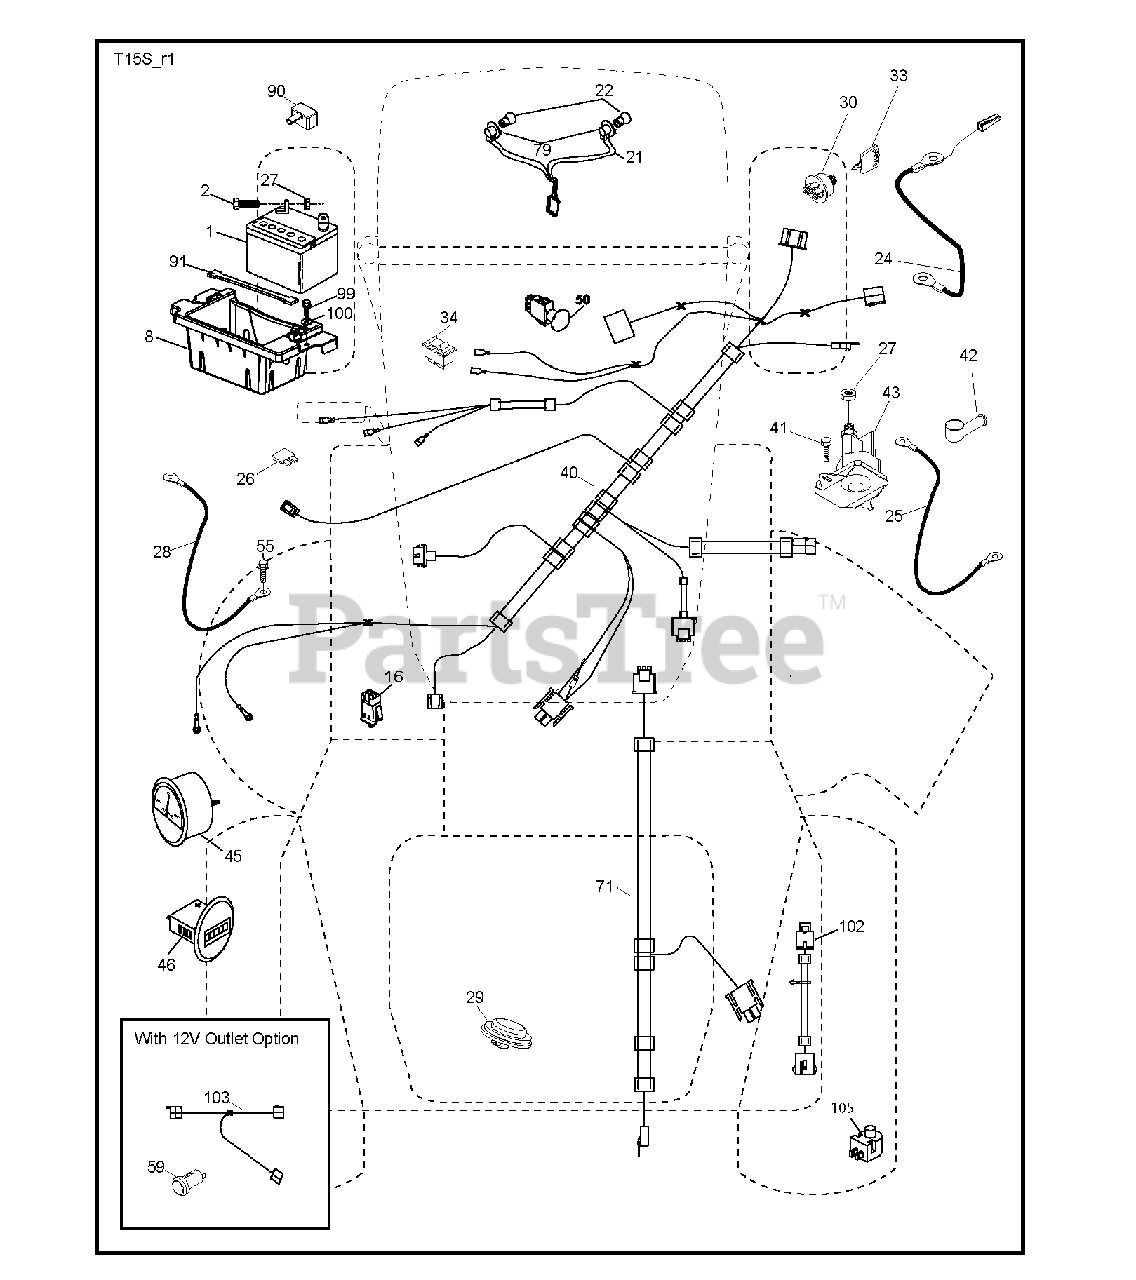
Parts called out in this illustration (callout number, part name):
1	REPL BY 532 12 38-99
8	BOX.BATTERY.MOUNT.FRONT.LT
16	SWITCH INTERLOOK PUSH-IN
21	HARNESS.LIGHT W/4152J BULBS
22	LIGHTBULB
24	CABLE.BATT.POS.WIRE.TG.DA SOL
25	CABLE.STARTER.6G.BL/RED.17.5
26	FUSE 20AMP
27	NUT
28	CABLE GROUND 6 GA 21" 90T BLK
29	SWITCH.SEAT.DELTA.OPC.
30	SWITCH.IGN.DELTA.W.LGH.ROS
33	KEY.CHAIN.BLISTER.PACK.GEN.INT
34	SWITCH LT
40	HARNESS IGN. DASH
41	SCREW
42	TERMINAL COVER
43	SOLENOID.W/BRASS.PLUNG
50	PTO SWITCH
55	SCREW 5/16"
71	HARNESS-CHASSIS SUB
79	BULB HOLDER ASM.
90	COVER.TERMINAL.BATTERY
91	STRAP, BATTERY MOUNT
99	SCREW HEXWSHR 1/4-20X3/4
102	HARNESS PIGTAIL PCH TEX ROS
105	REVERSE SWITCH
